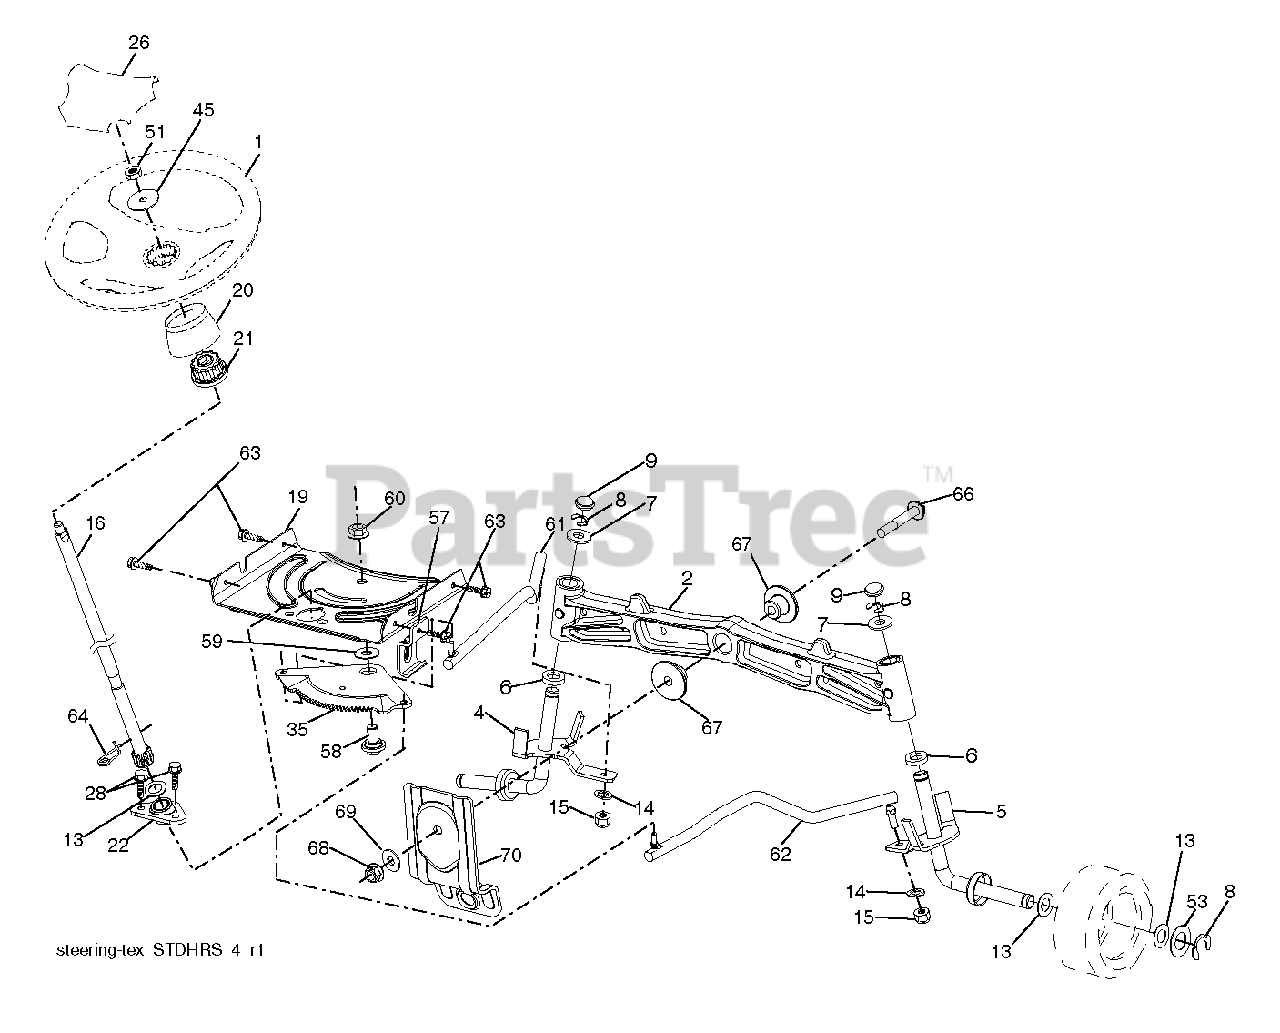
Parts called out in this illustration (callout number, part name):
1	WHEEL, STEERING
4	SPINDLE.WELDED.LH.15"T
5	SPINDLE.WELDED.RH.15"T
6	BRNG T
14	WASHER, LOCK 3/8
15	NUT CROWNLOCK 3/8-24
19	PLATE.STEER.DDL.NLT/NG
20	BOOT.STEERING.
21	ADAPTER, WHEEL STNG
22	STEERING.SUPT.LOWER.
26	INSERT, WHEEL STEERING
28	SCREW, 3/8-16X3/4
35	GEAR.SECTOR.PLATE.DDL.
57	BRKT.UPSTOP.GT/LT.TEX
58	BOLT.SHOULDER.SECTOR.P
59	WASHER.THURST.SECTOR.S
60	NUT FLANGE LOCK 5/8-11
61	DRAGLINK.LH.BALLSTUD.D
62	DRAGLINK.RH.BALLSTUD.D
63	SCREW
64	RETAINER.CLIP.SPRING.S
66	BOLT HEX FGHD 7/16-14 X 3 SERR
67	BUSHING.PM.FRONT AXLE
68	NUT.LOCK.FLANGE.7/16
69	WASHER.1.5X.505X.118
70	BRKT.DECK.SUSPENSION.F
